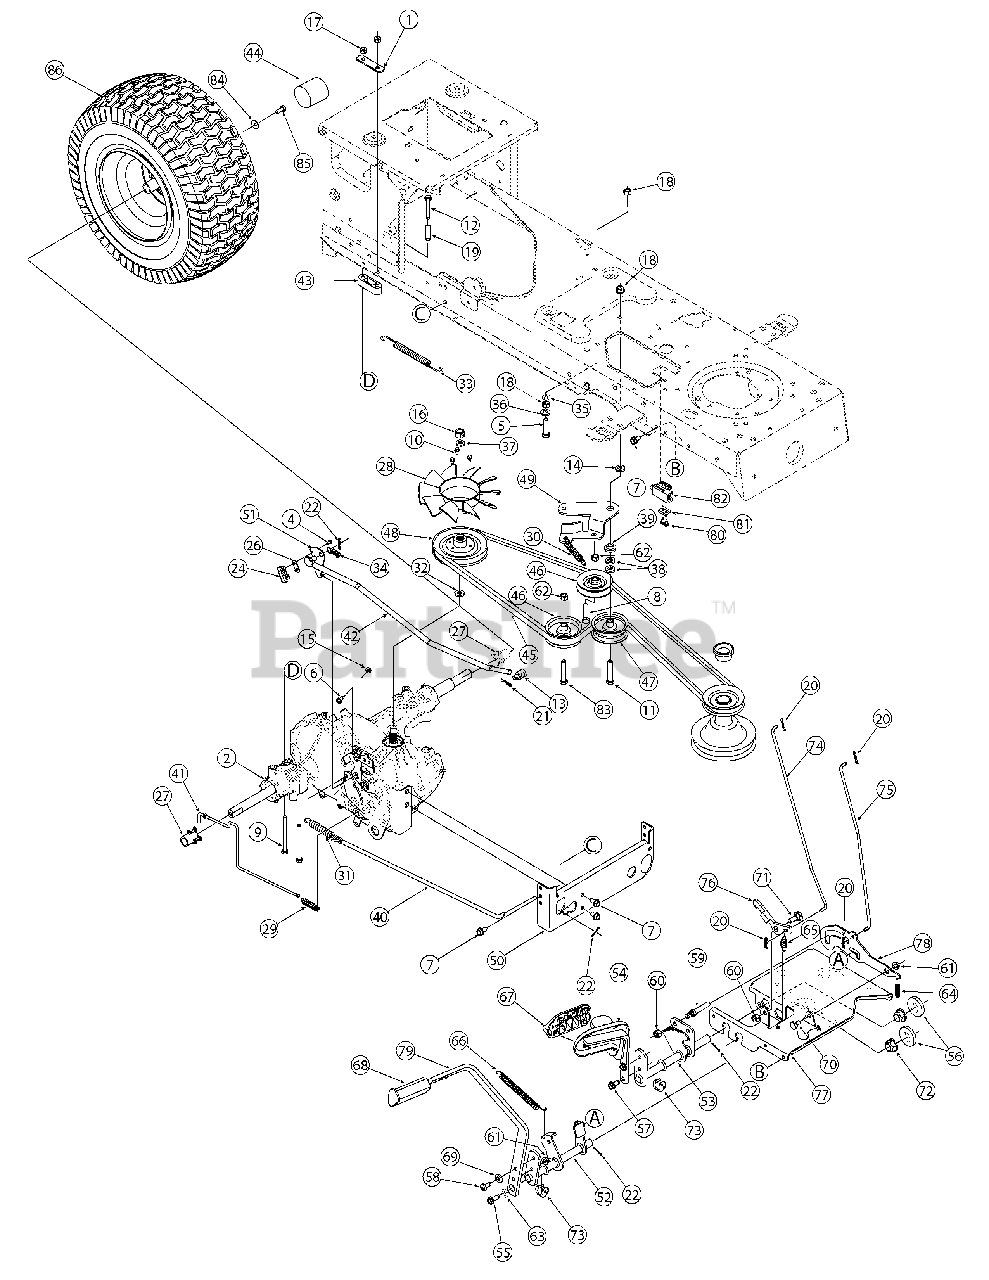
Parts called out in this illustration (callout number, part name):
2	Hydrostatic Transmission
4	Hex Wash HD AB S-Tapp Scr #8-.50
5	Hex Screw 3/8-16 x 1.50
6	Hex Wash HD Tapp Scr 1/4-20 x .375
7	S-Tapp Scr 5/16-18 x .75
8	Hex Washer Scr 3/8-16 x 1.25
9	Hex Bolt 5/16-18 x 3.5" Lg.
10	Hex Tap Scr #12 x .375
11	Hex Bolt 3/8-16 x 2.25" Lg.
12	Hex Wash HD Bolt 1/4-20 x 1.50" Lg.
13	Adjustment Ferrule 3/8-24
14	Flat Washer .385 ID X 1.0 OD X .130
15	Hex Cent-L Nut 1/4-20
16	Hex Nut 1/2-20 Grade 5
17	Flange Locknut 5/16-18 Gr. F, Nylon
18	Hex. Flanged L-Nut 3/8-16 Gr. F
19	Spacer .260 x .375 x 1.030 Lg.
20	Hex Nut 3/8-16
21	Cotter Pin 3/32 x .75
22	Cotter Pin 3/32 dia x 1.00 Lg.
24	Short Spring Switch
26	Insulator Nut Plate
27	Sleeve 0.765 x 1.5
28	Fan
29	Extension Spring .47 OD x 2.03 Lg.
30	Extension Spring
31	Ext. Spring .59 OD x 4.00 Lg.
33	Extension Spring .75 x 5.39
34	Extension Spring 3/8 x 1.44
35	L-Wash 3/8 ID
36	Flat Washer .385 ID x .87 OD x .06
37	L-Washer 1/2" ID
38	Flat Washer .406 ID x .812 OD x .134
39	Shoulder Spacer
41	Hydrostatic Bypass Rod
42	Hydrostatic Control Rod
43	Transaxle Spacer
45	"V" Belt
46	Pulley, V-Type Drive 3.06
47	Idler Pulley, Flat 2.75 OD
55	Hex Wash Taptite 5/16-18 x .875
56	Flat Washer .640 ID x 1.24 OD x .06
57	Hex Wash. Hd. Scr. 5/16-18 x .75 Lg.
58	Screw 5/16-18 x .75
59	Pin 3/8-16 x 2.68 Lg.
60	Flange Lock-Nut 3/8-16 Gr. F Nylon
61	Hex Flange L-Nut 5/16-18
62	Hex Jam Nut 7/16-20
63	L-Wash 5/16 ID
64	Com pression Spring
65	Extension Spring, .50 OD x 1.41
66	Extension Spring, .50 Dia. x 6.37
67	AutoDrive Pedal Pad
69	Flat Washer .312 ID x .75 OD
70	Shld. Scr .437 Dia x .162 Lg.
71	Shoulder Screw .500 x .25
72	Hex Flange Bearing .630 ID
73	Hex Flanged Bearing .628 ID
74	Brake Lock Rod
75	Cruise Control Rod
76	Cruise Control Latch
78	Drive Lockout Bracket
81	Switch Plate
82	Interlock Switch
83	Hex L-Wash HD Scr 3/8-16 x 1.5
84	Cupped Washer .345 ID x .88 OD x .060
85	Hex L-Bolt 5/16-24 x .75 Gr. 5
